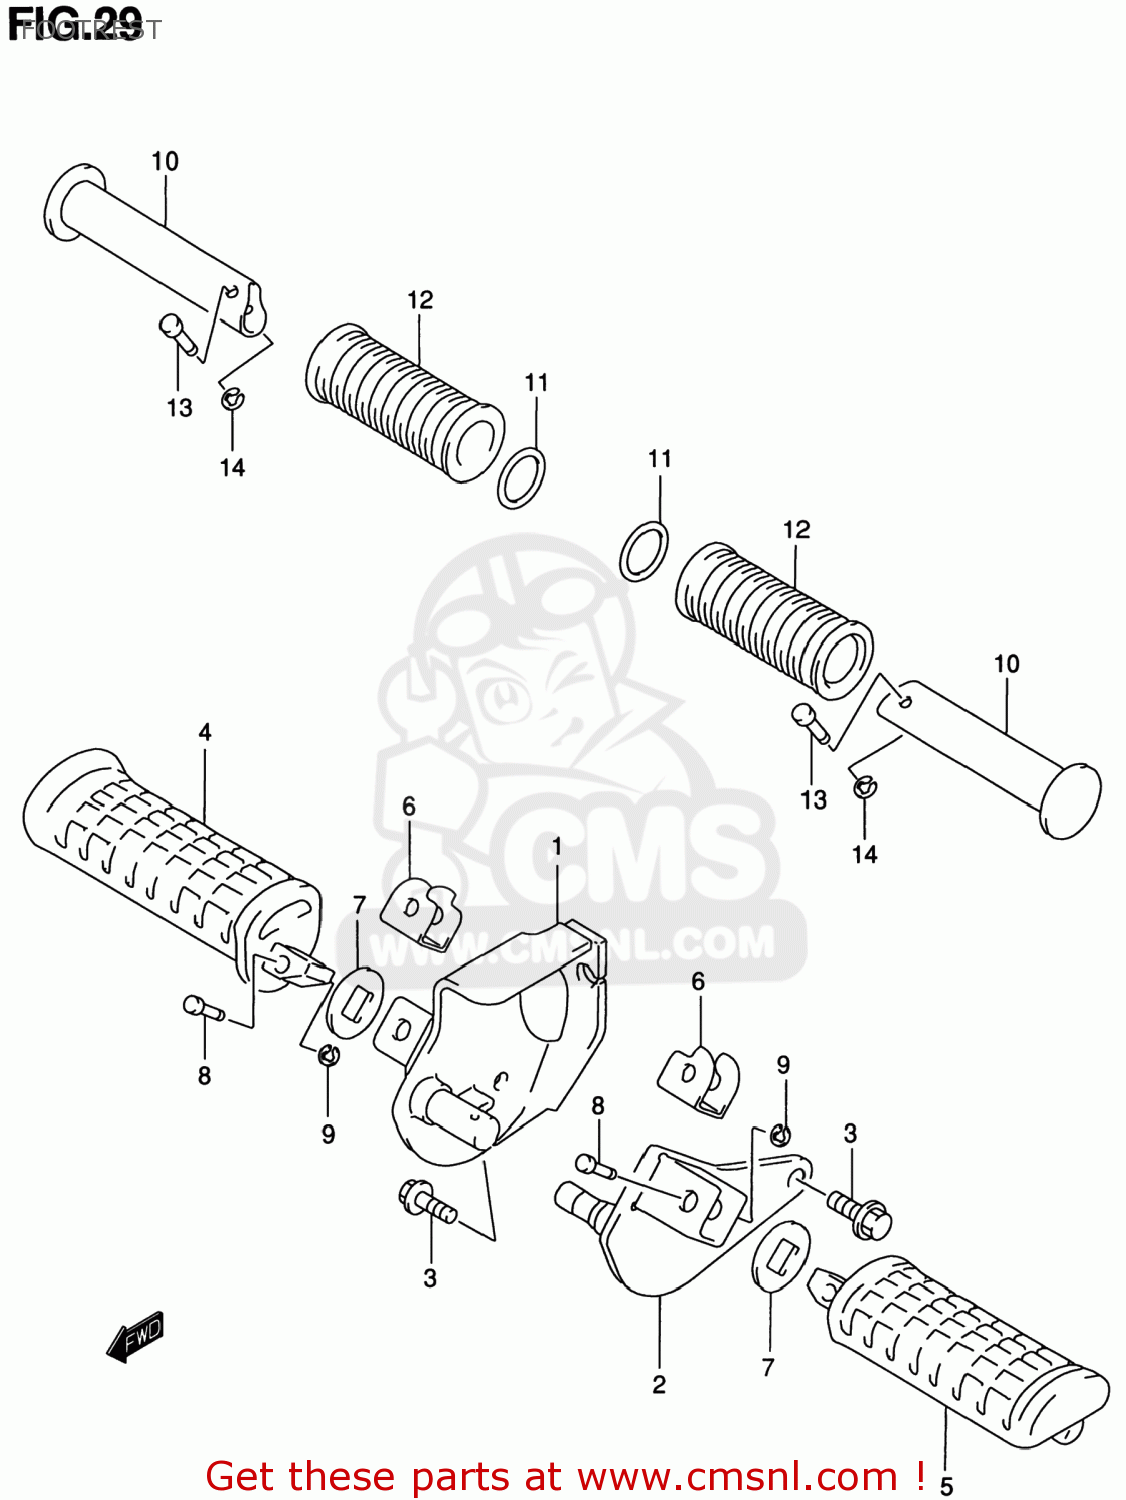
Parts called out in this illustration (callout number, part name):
1	BRACKET,FR FOOTREST,R
2	BRACKET,FR FOOTREST,L
3	BOLT
4	RUBBER,FRONT FOOTREST,RIGHT
5	RUBBER,FRONT FOOTREST,LEFT
6	CUSHION,FR FOOTREST
7	WASHER,FOOTREST RUBBER
8	PIN
9	E-RING
10	BAR,PILLION FOOTREST
11	WASHER(19.5X32X2)
12	RUBBER,PILLION FOOTREST
13	PIN,PILLION FOOTREST
14	E-RING
